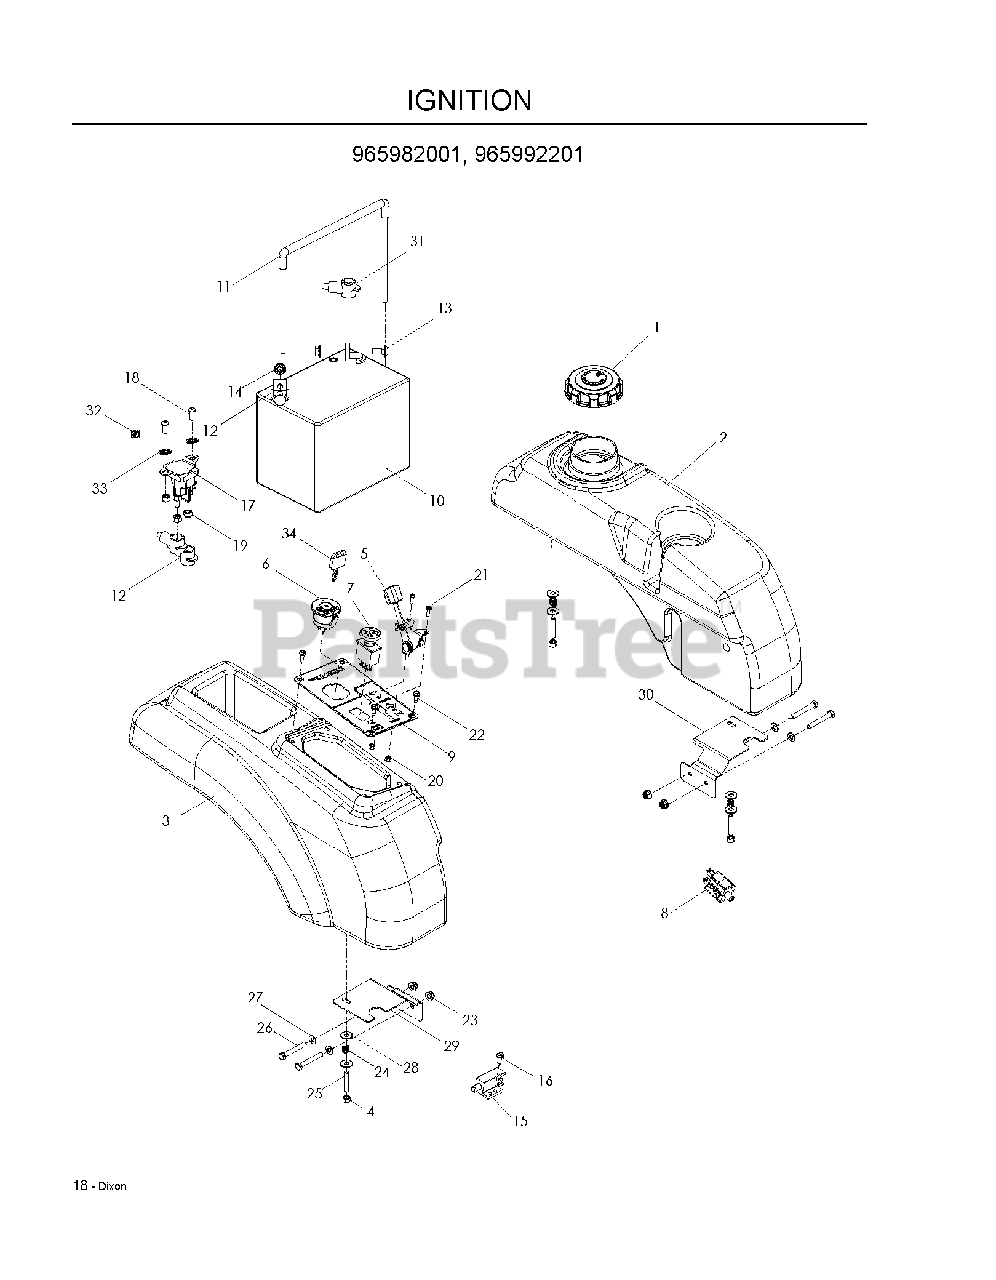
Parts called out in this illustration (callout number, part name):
2	FUEL TANK ASM LH
3	FENDER RH
4	NUT 5/16 NYLOC
5	THROTTLE CABLE
6	IGNITION SWITCH
7	SWITCH, BLADE
8	SWITCH, BRAKE 3P
9	DECAL, CONTROL PANEL
10	BATTERY, 12 V 330 AMP TBR
11	BATTERY TIE DOWN ASSEMBLY
12	TERMINAL COVER-SM
13	BOLT 5/16C X 3/4" CARRIAGE
14	NUT 5/16C WHIZ
15	SWITCH, INTERLOCK
16	SCREW #10 X 1/2 SELF TAPPING
17	SOLENOID
18	SCR 1/4-20 X 5/8 BTN SKT HD ZD
19	NUT 1/4-20 NYLOC
20	NUT 10-24 NYLOC
21	SCREW #10-24 X 5/8
22	SCREW 1/4 X 5/8
23	5/16-18 NYLOC FLANGE NUT
25	STUD, 5/16C
26	CAPSCREW
27	FLAT WASHER 5/16 SAE
28	WASHER 5/16 FLAT
29	SUPPORT, TANK LT BLK
30	SUPPORT, TANK, RT BLK
31	INSULATOR
32	JAM NUT 1/4C
33	WASHER 1/4 INT TOOTH
34	KEY
